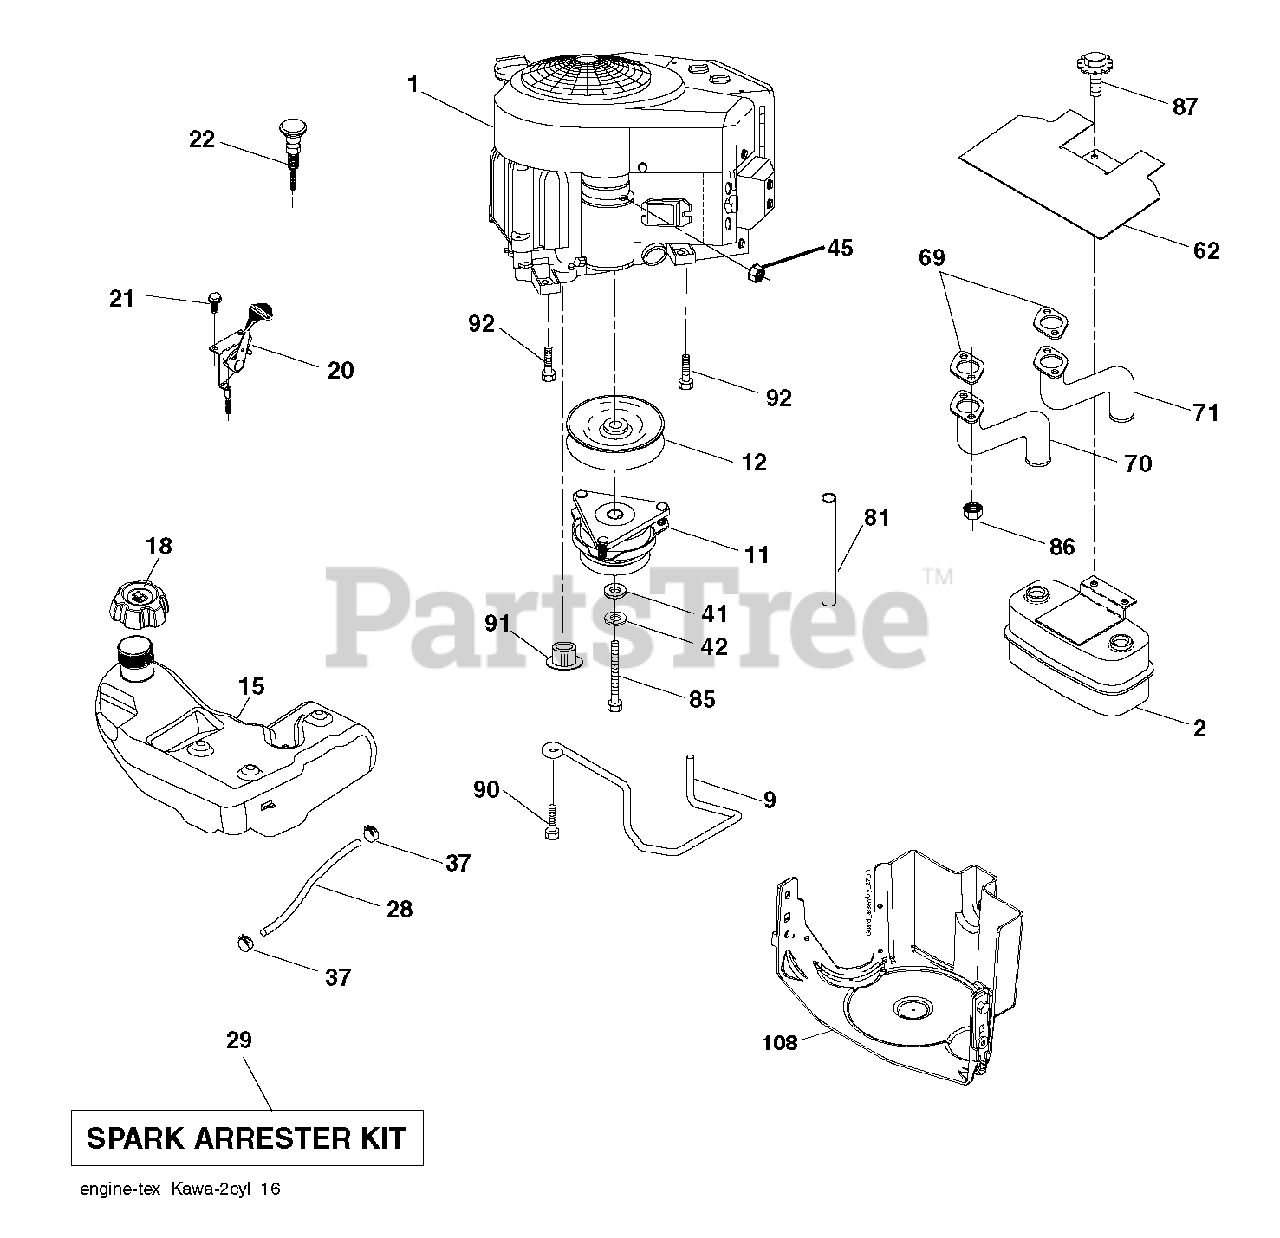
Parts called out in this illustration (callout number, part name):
2	MUFFLER.ASM.TWN.EXTNDED.DFLCTR
9	KEEPER.BELT.ENGINE.4.2
11	CLUTCH MZ ZTR GT.48/54"1.125"
12	PULLEY ENGINE
15	TANK.FUEL.4GAL
18	CAP.FL.R.3'N/CARB.H.CROWN.498
20	THROTTLE CONTROL
21	SCREW.#10 X 0.750.BOS
22	CONTROL.CHOKE.ERGO.PUSH-IN.BLA
28	REPL BY 532 00 85-43
29	KIT.SPARK ARRESTOR 794945 B&S
37	HOSE CLAMP
42	LOCKWASHER
45	NUT
62	SHIELD.HEAT.MUFFLER
70	TUBE.EXHAUST.LH.FR961/FR730
71	TUBE.EXHAUST.RH.FR961/FR730
81	TUBE, DRAIN OIL ASM.
85	BOLT HEX 7/16-20 X 3.75 GR. 5
86	NUT.HEX.FLANGE.TOPLOCK
87	BOLT, 5/16-18 X 1 3/4
90	SCREW 3/8-16X1
91	BUSHING.1.375OD
92	SCREW 3/8-16X1
